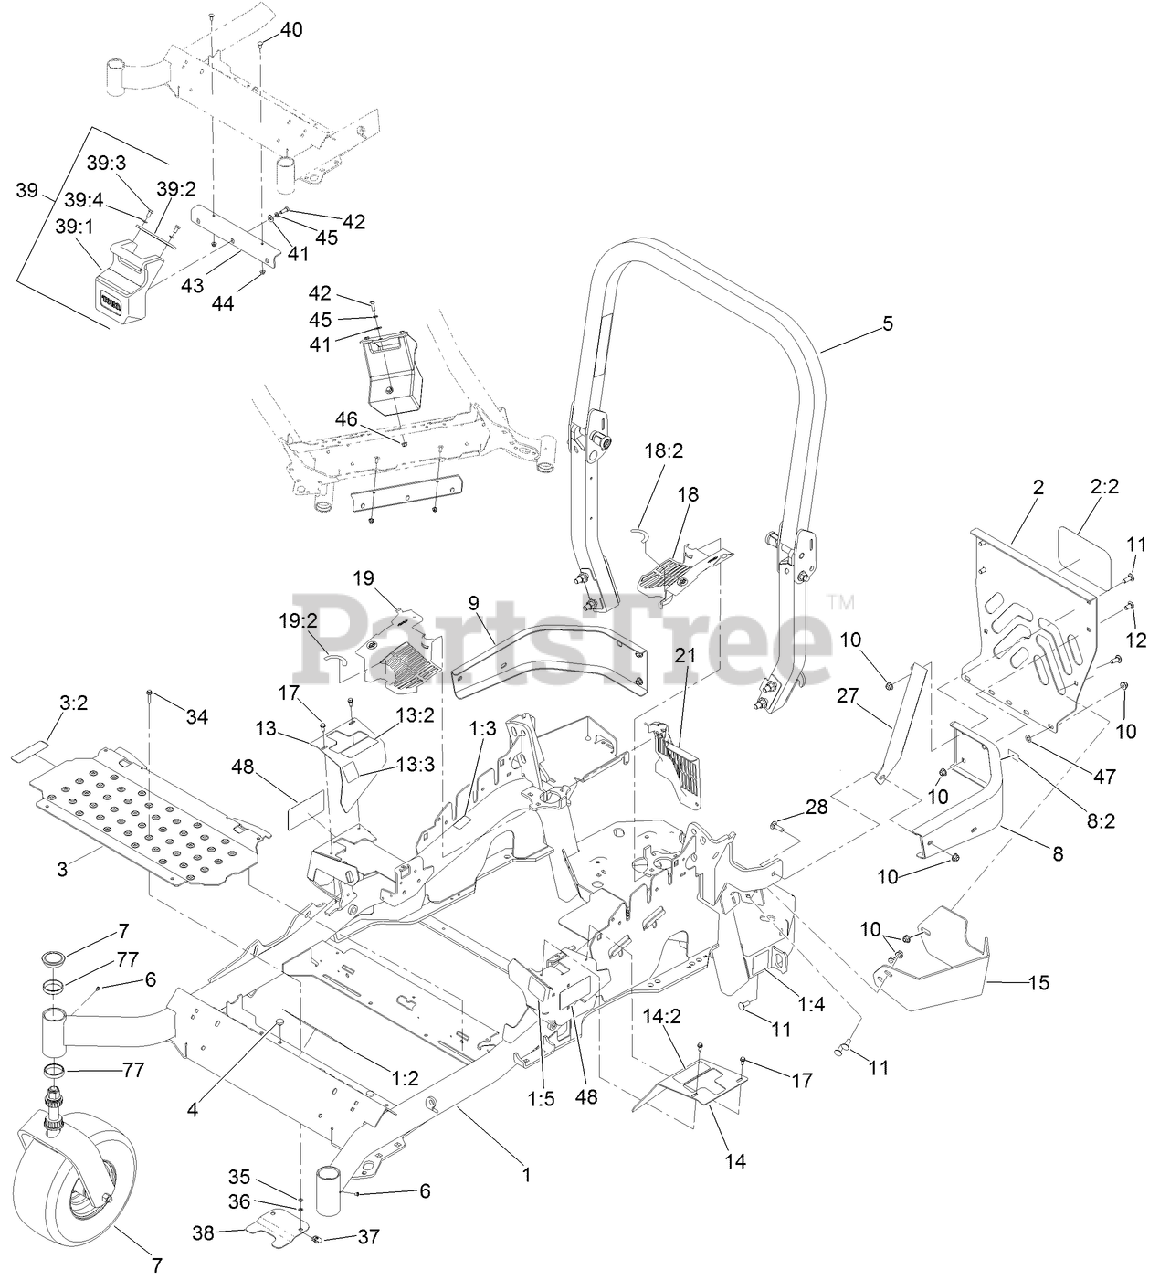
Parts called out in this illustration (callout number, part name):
1	MAIN FRAME ASM
1:2	DECAL-DANGER
1:3	DECAL-WARNING
1:4	DECAL-HAZARD, PINCHED FINGER
1:5	DECAL-FUEL FILL, CE
2	REAR GUARD ASM
2:2	DECAL
3	FLOORPAN ASM
3:2	DECAL-MISSING, COVER
4	BUMPER
5	ROPS ASM
7	Caster Wheel ASM
8	LH REAR BUMPER ASM
8:2	DECAL-WARNING
9	BUMPER-RH
10	NUT-HF, NI
11	SCREW-CARR
12	SCREW-CARR
13	RH MOTION CONTROL COVER ASM
13:2	DECAL-CONTROL, MOTION
13:3	DECAL-PARK BRAKE, CE
14	LH MOTION CONTROL COVER ASM
14:2	DECAL-CONTROL, MOTION
15	GUARD-MUFFLER
17	SCREW-HWH
18	LH HYDRO GUARD ASM
18:2	DECAL-HYDRO OIL
19	RH HYDRO GUARD ASM
19:2	DECAL-HYDRO OIL
21	GUARD-HYDRO, REAR (RH)
28	BOLT-CARR
34	SCREW-HHF
35	WASHER-FLAT
36	NUT-RETAINER
38	ADAPTER-CAPTIVE
39	WEIGHT ASM
39:1	WEIGHT-43 LB
39:2	TAB-SUPPORT, WEIGHT
39:3	SCREW-HH
39:4	WASHER-LOCK
40	SCREW-CARR
41	WASHER-FLAT
42	SCREW-HH
43	BRACKET-MOUNT, WEIGHT
44	NUT-HF, NI
45	WASHER-LOCK
46	NUT-HF, NI
47	NUT-PUSH
77	CUP-BEARING
